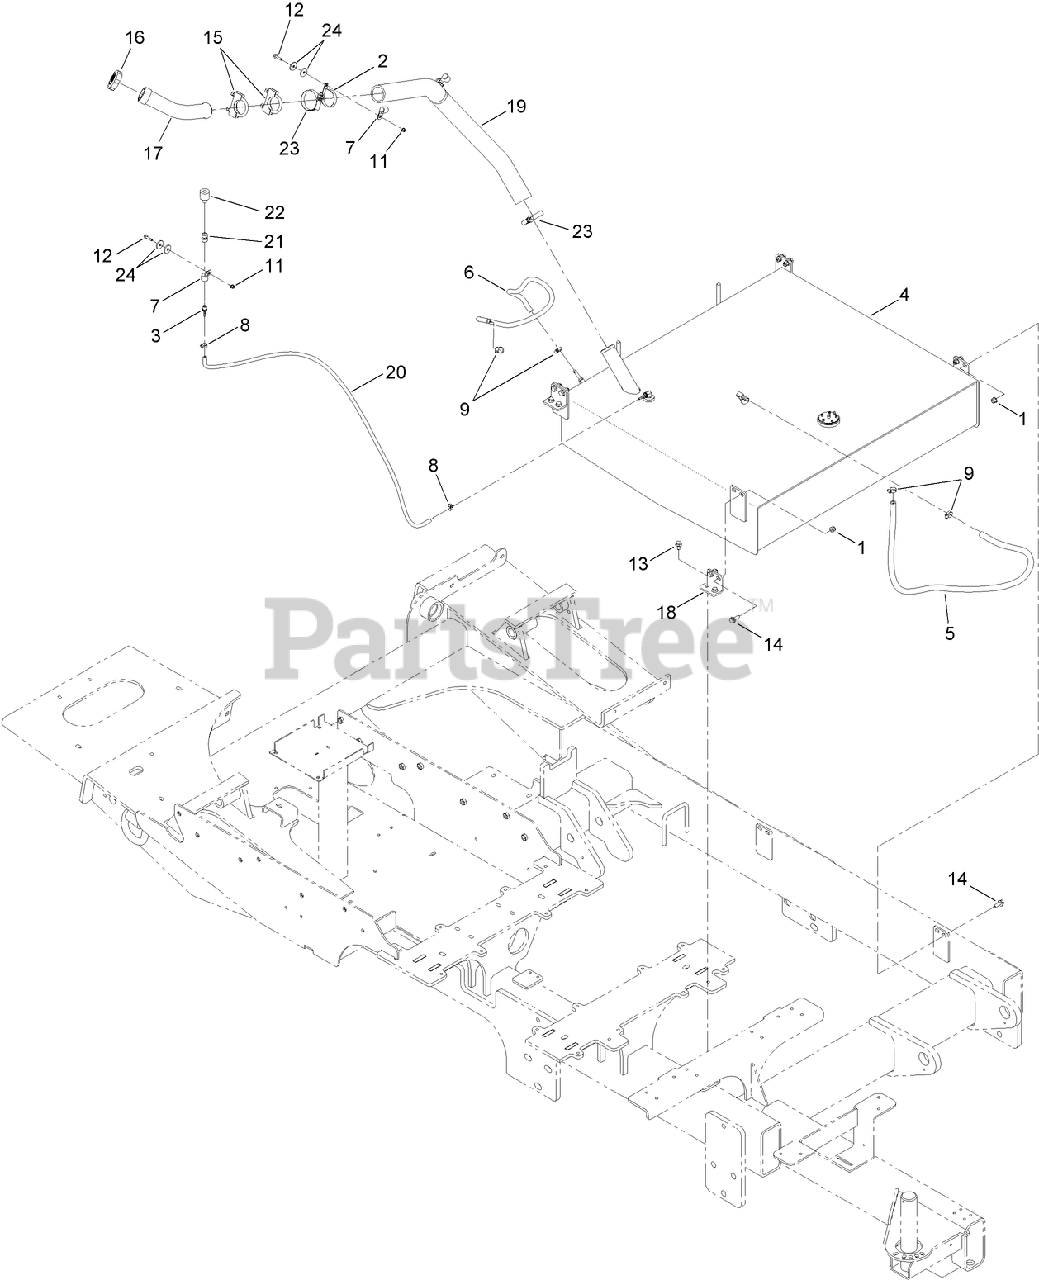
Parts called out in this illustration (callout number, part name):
1	NUT-LOCK, NI
2	R-Clamp
3	FITTING-STRAIGHT
4	FUEL TANK ASM
5	HOSE-FUEL
6	HOSE-FUEL
7	CLAMP-R
8	CLAMP-WORM
9	CLAMP-HOSE
11	NUT-FLANGE, NI
12	SCREW-HHF
13	SCREW-HHF
14	SCREW-HHF
15	BOLT-U, CLAMP
16	CAP-FUEL (W/LOCK)
17	NECK-FILLER, FUEL
18	PLATE-MOUNTING, TANK
19	HOSE-FUEL, TANK FILL
20	HOSE-FUEL
21	COUPLING-PIPE (NPTF)
22	BREATHER
23	Clamp-Hose
24	Washer-Flat
